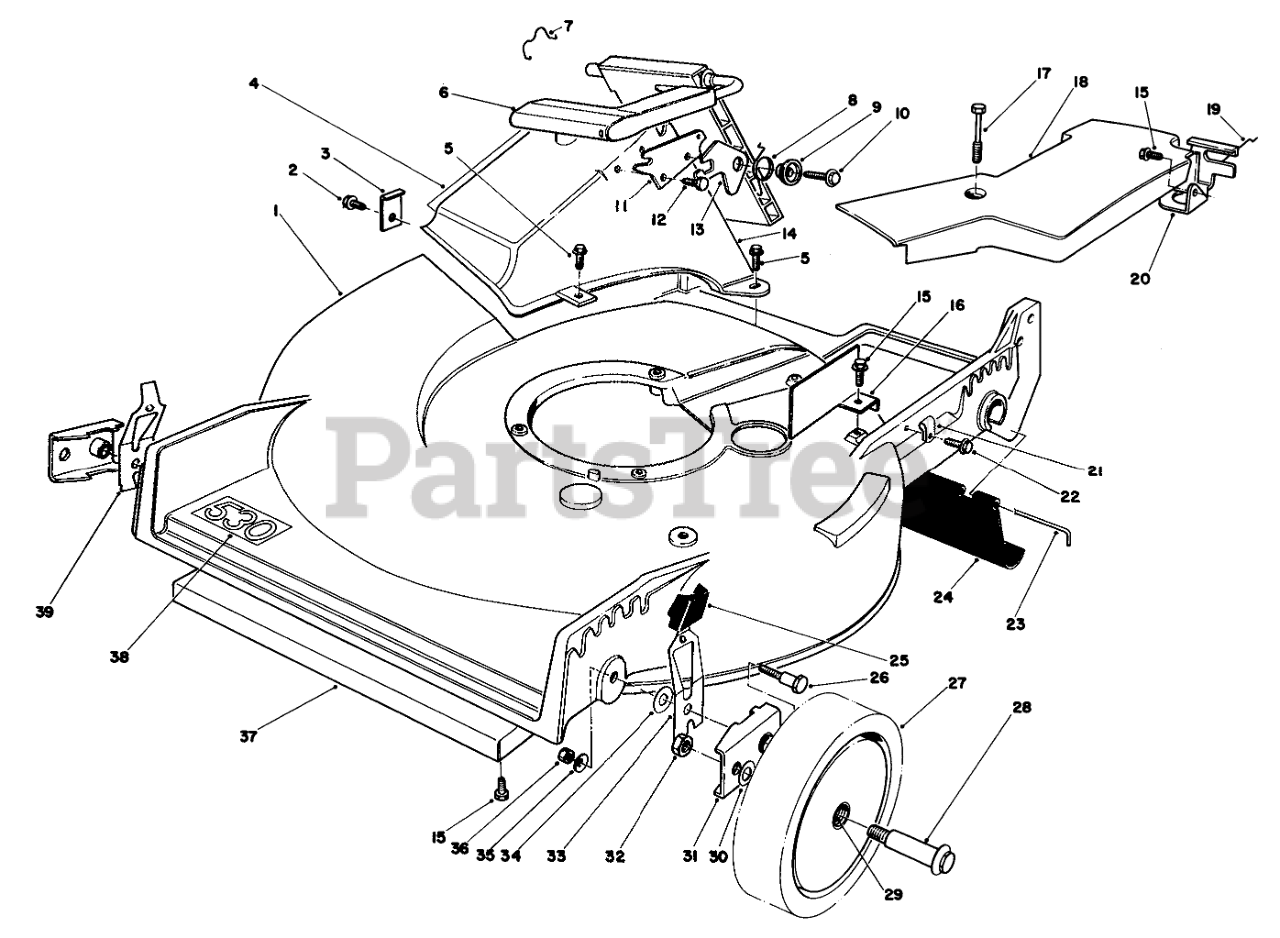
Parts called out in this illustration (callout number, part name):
1	21 SP RB HSG/DECAL
2	SCREW
3	TUNNEL CLIP
4	ATTENTION DECAL
5	SCREW-HWH
6	Discharge Door Assembly
7	DOOR RET SPRING
8	TORSION SPRING
9	Latch Spacer
10	SCREW-HWH
11	DOOR LATCH PLATE
12	SCREW-PLASTITE
13	Latch-Door
14	Tunnel Discharge
15	SCREW-HWHTF
16	Shield-Muffler
17	SCREW-HHFTF
18	Cover-Belt
19	RETAINER-CABLE
20	Bracket-Traction Adj.
21	CLAMP-CABLE
22	SCREW
23	ROD-SHIELD
24	SHIELD-TRAILING
25	KNOB-ARM
26	PIVOT SCREW
27	Wheel & Tire Assembly (Incl. Ref. #29)
28	WHEEL BOLT
29	BUSHING
30	WASHER
31	HP PIVOT ARM ASM
32	NUT-LOCK
33	L. HP SPRING ARM ASM
34	WASHER-PIVOT
35	WASHER-BELLEVILLE
36	NUT-LOCK, NI
37	Shield-front
38	Decal-530
39	R HP SPRING ARM ASM
